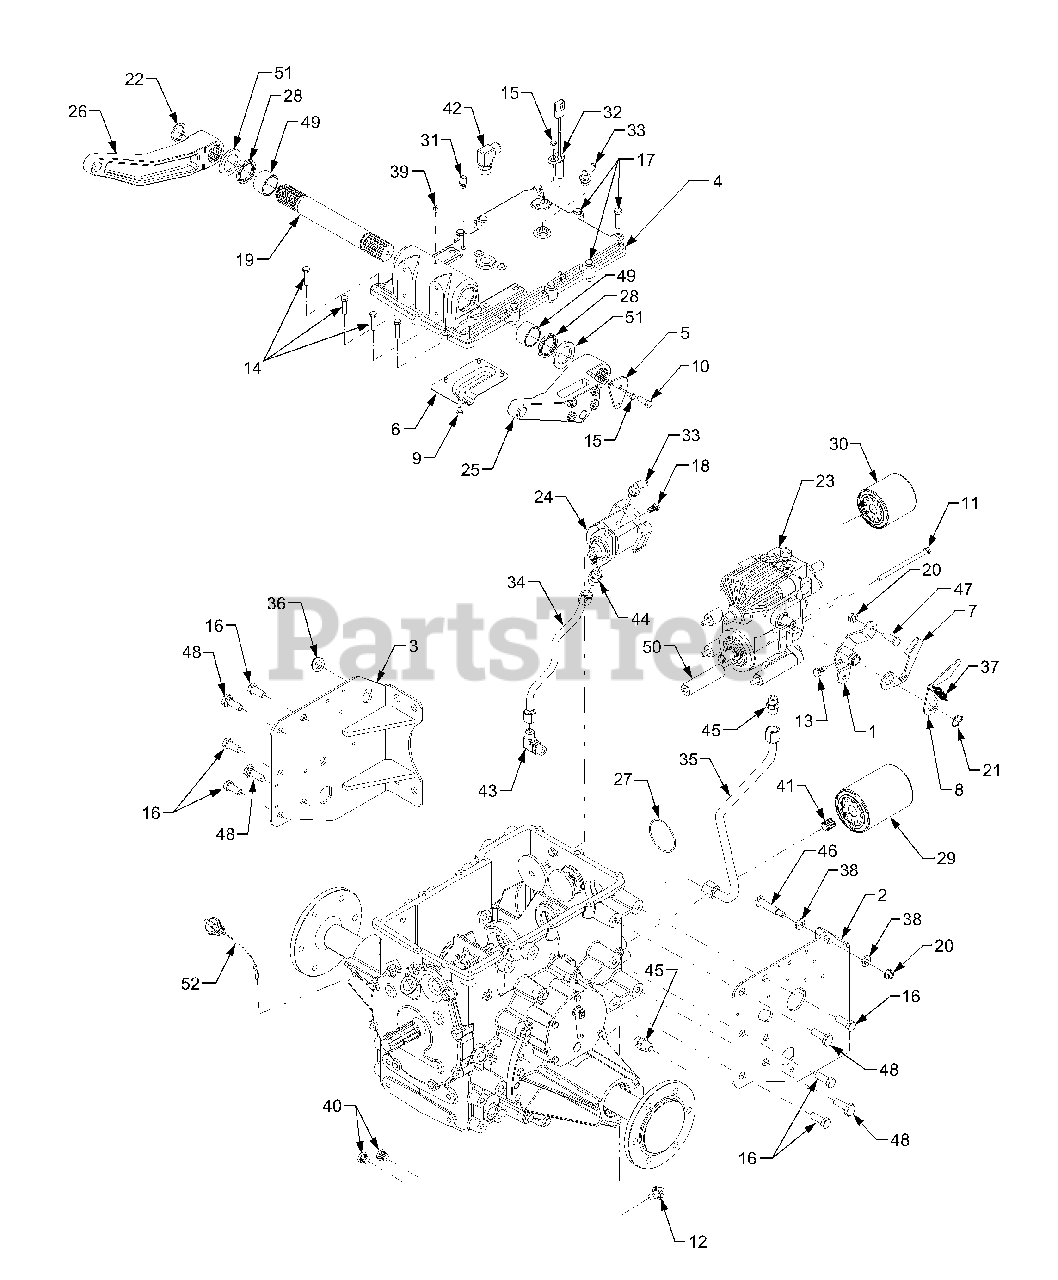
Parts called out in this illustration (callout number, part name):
1	Arm, Hydro Control
2	Bracket, Transmission Mtg. RH
4	Cover, Transmission Housing
5	Plate, Feedback
6	Baffle, Oil
7	Arm, Neutral RH
8	Arm, Neutral LH
9	Screw, Hex Cap, 1/4-20 x .375 GR5
10	Screw, Hex Cap Lock, 3.8-24 x 1.0 GR5
11	Screw, Hex Cap, 5/16-18 x 5.25 GR5
12	Screw, Plug, M14 x 1.5 x .827
13	Screw, Hex Special Set, 5/16-18 x .625
14	Screw, Hex Cap, 3/8-16 x 1.25 GR5
15	Screw, Hex Cap, 1/4-20 x .5 GR5
16	Screw, Hex Cap, 1/2-13 x 1.25 GR5
17	Screw, Hex Cap Lock, 3/8-16 x 1.5 GR5
18	Screw, Low Hd. Cap, 3/8-16 x .75
19	Shaft, Rock
20	Nut, Hex Flange Lock, 3/8-16
21	Ring, Retaining
22	Ring, Retaining
23	Pump, Hydrostatic Transmission
24	Pump, Auxiliary Hydraulic
25	Arm, Upper Hitch RH
26	Arm, Upper Hitch LH
27	O-Ring, 2.987 ID x .103 Dia
28	Seal, Oil, 1.5 x 2.0 x .25
29	Filter, Oil, Hydraulic System
30	Filter, Oil
31	Breather, Transmission
32	Sensor, RPM
33	Fitting, 90 degrees
34	Tube, Auxiliary Pump Suction
35	Tube, Hydro Suction
37	Spring, Extension
38	Washer, Flat, .406 x 1.0 x .105
39	Fitting, Grease
40	Plug, Fitting
41	Fitting, Filter Nipple
42	Fitting, 90 degrees
43	Fitting, 90 degrees
44	Fitting, Straight
45	Fitting, Straight
46	Screw, Shoulder, .498 Dia x 1.45
47	Screw, Shoulder, .50 Dia x .685
48	Screw, Shoulder, .625 x .18: 1/2-13
49	Bearing, Sleeve, 1.52 x 1.75 x 1.0
50	Spacer, .40 x 1.0 x 3.9
51	Spacer, 1.52 x 2.25 x .188
